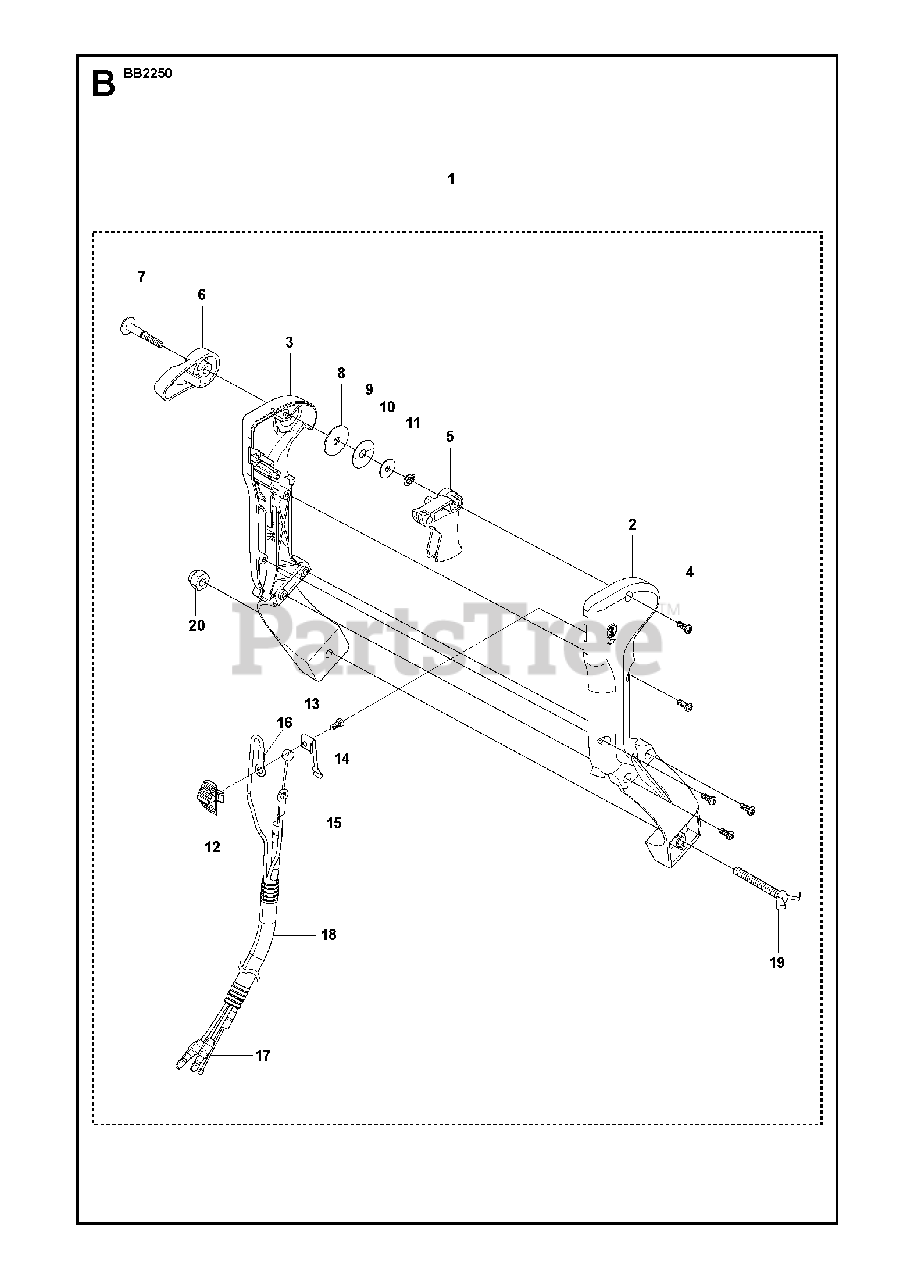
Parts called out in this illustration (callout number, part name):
2	COVER
3	RP_CASE (RPLS T402325110)
4	SCREW 4X14(T)
5	LEVER, THROTTLE(T)
6	RP_LEVER (RPLS T402325430)
7	RP_SHAFT(T)
8	WASHER(T)
9	RP_SPRING WASHER
10	RP_WASHER
11	RP_CLIP(T)
12	RP_SWITCH(T)
13	SPRING (RPLS T402325720)
14	RP_SCREW 4X10(T)
17	CABLE
19	RP_BOLT, WING
20	NUT
